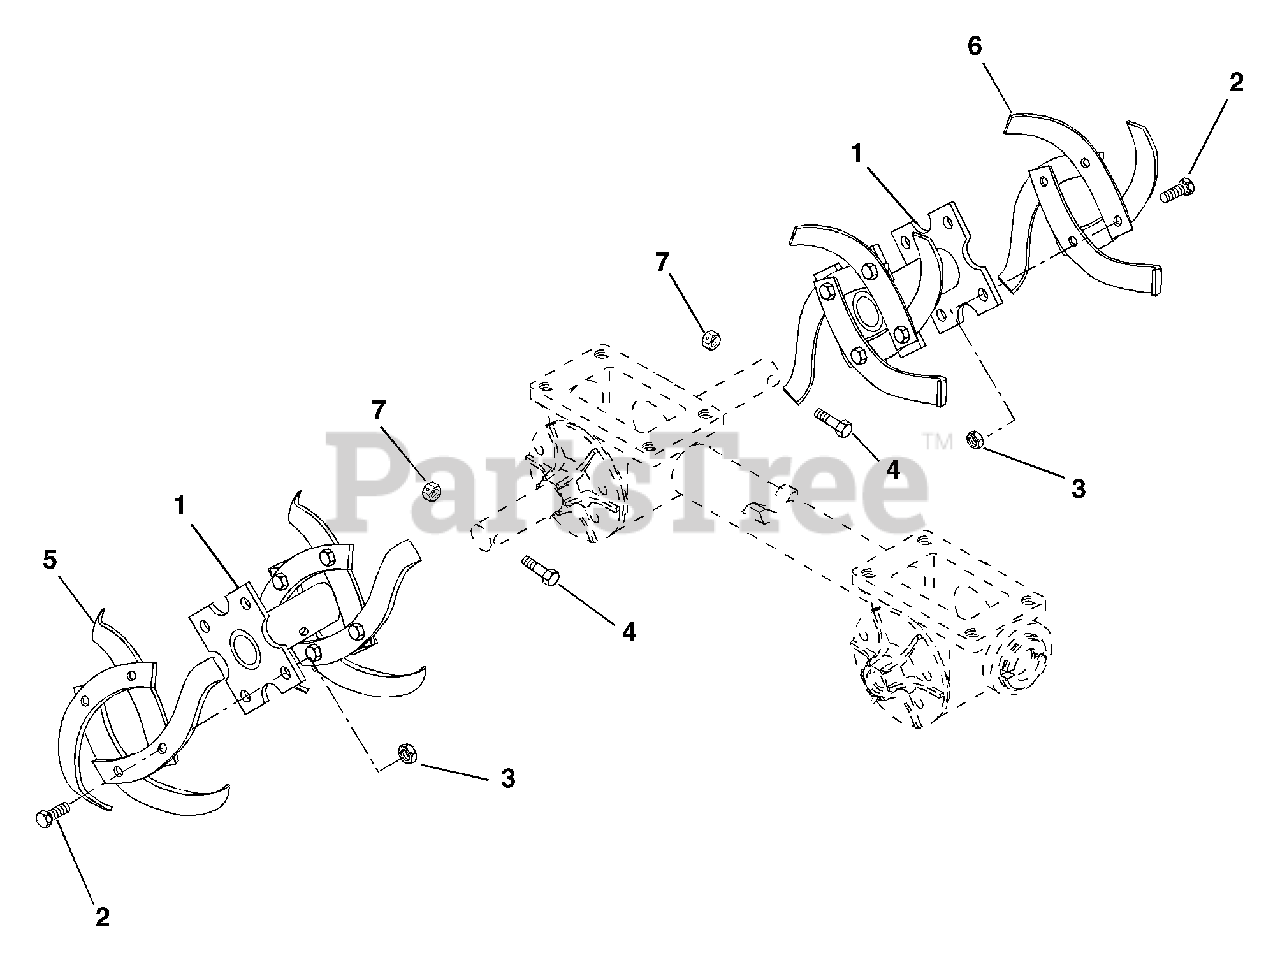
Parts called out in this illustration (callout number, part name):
1	HOLDER - BOLO TINE
2	@BLT-HEX .38-16X1.00 GR5 YWZC
3	@NUT-LK-CTR-JAM .375-16 YWZC
4	@BLT-HEX .38-16X1.75 GR5 YWZC
5	RH BOLO TINE
6	LH BOLO TINE
7	@NUT-LK-CTR .38-16 YWZC
